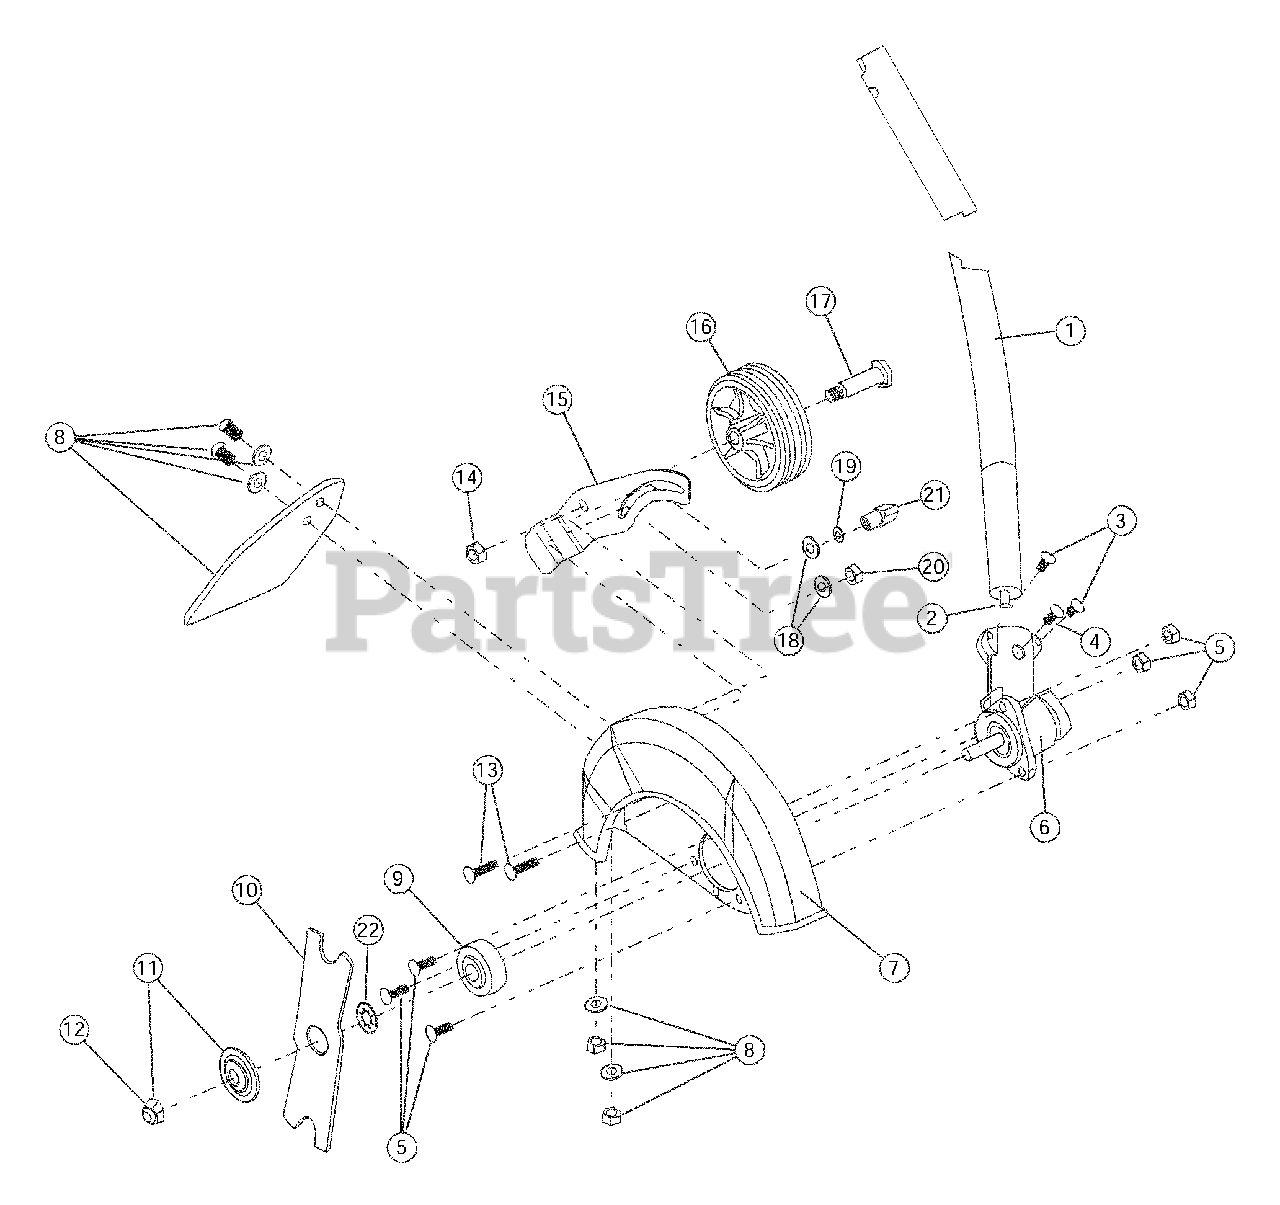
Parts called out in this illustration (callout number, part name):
1	Boom Assembly
2	Drive Shaft
3	Boom Mounting Hardware
4	Anti-Rotation Screw
5	Guard Mounting Hardware
6	Gearbox Assembly
7	Blade Guard
8	Deflector w/Hardware
9	Spacer
10	Blade
11	Blade Clamp Washer
12	Blade Retainer Nut
13	Wheel Bracket Mounting Bolt
14	Nut
15	Edger Guide
17	Shoulder Bolt
19	Washer
20	Nut
21	Edger Guide Knob
22	Palnut
